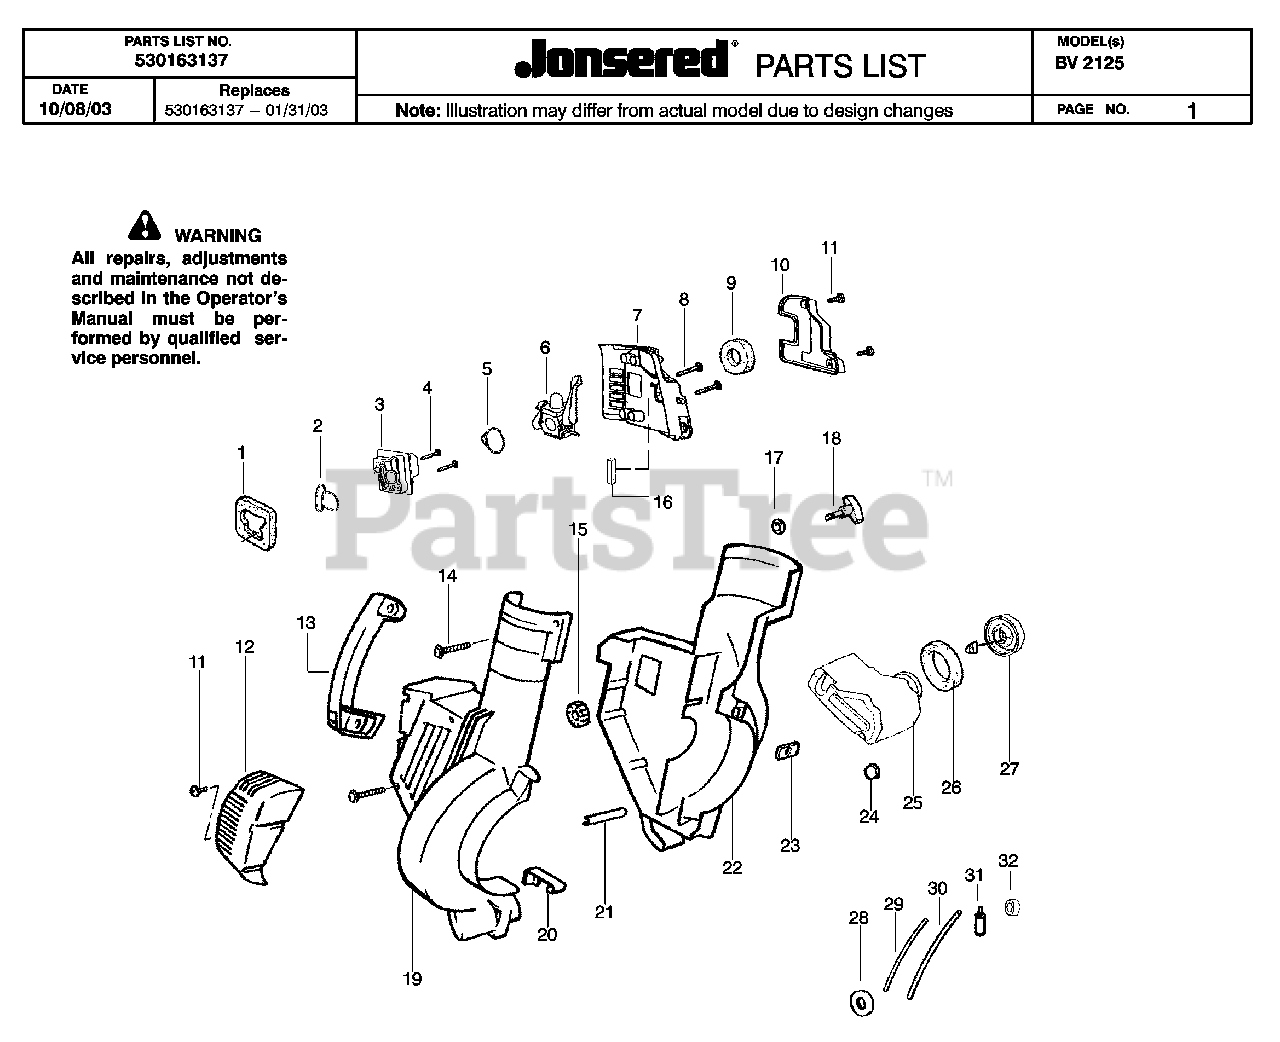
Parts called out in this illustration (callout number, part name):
2	GASKET KIT
5	GASKET KIT
6	CARB
6	KIT CARB ASSY C1Q-W11
11	SCREW FILTER PLATE
14	SCREW-10-14 X 13/16 (PL
24	CRANKCASE ISOLATOR
31	FUEL PICK-UP ASSY
